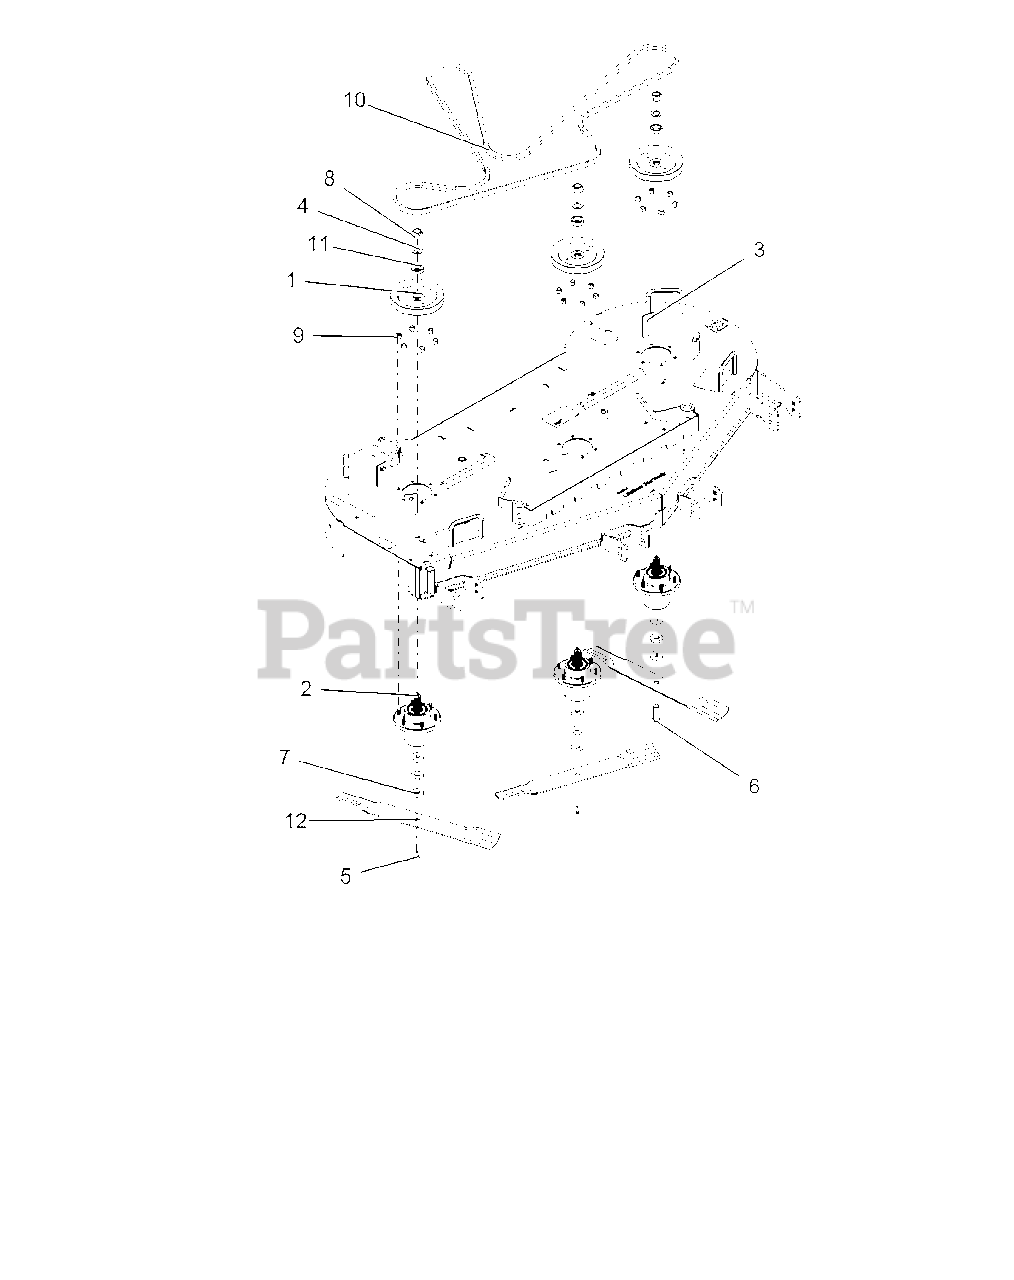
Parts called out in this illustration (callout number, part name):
1	PULLEY, SPINDLE 6.34 OD
2	ASSY, SPINDLE HOUSING
3	DECK, WITH DECALS 61"
4	WASHER, .75X1.3125X.120
5	BLT-HEX .25-20X.75 GR5 YWZC
6	BLT-HEX .62-11X2.00 GR5 YWZC
7	WSHR-FL-STL .630X1.50X.25 YWZC
8	LOCKNUT, 3/4-16 CROWN GR5 Y
9	NUT-LK-NYL .38-16 YWZC
10	BELT, 61" FLWLK
11	SPACER, 1.500X1.000X.510 Y
12	BLADE, 21.000 X .80 LIFT
